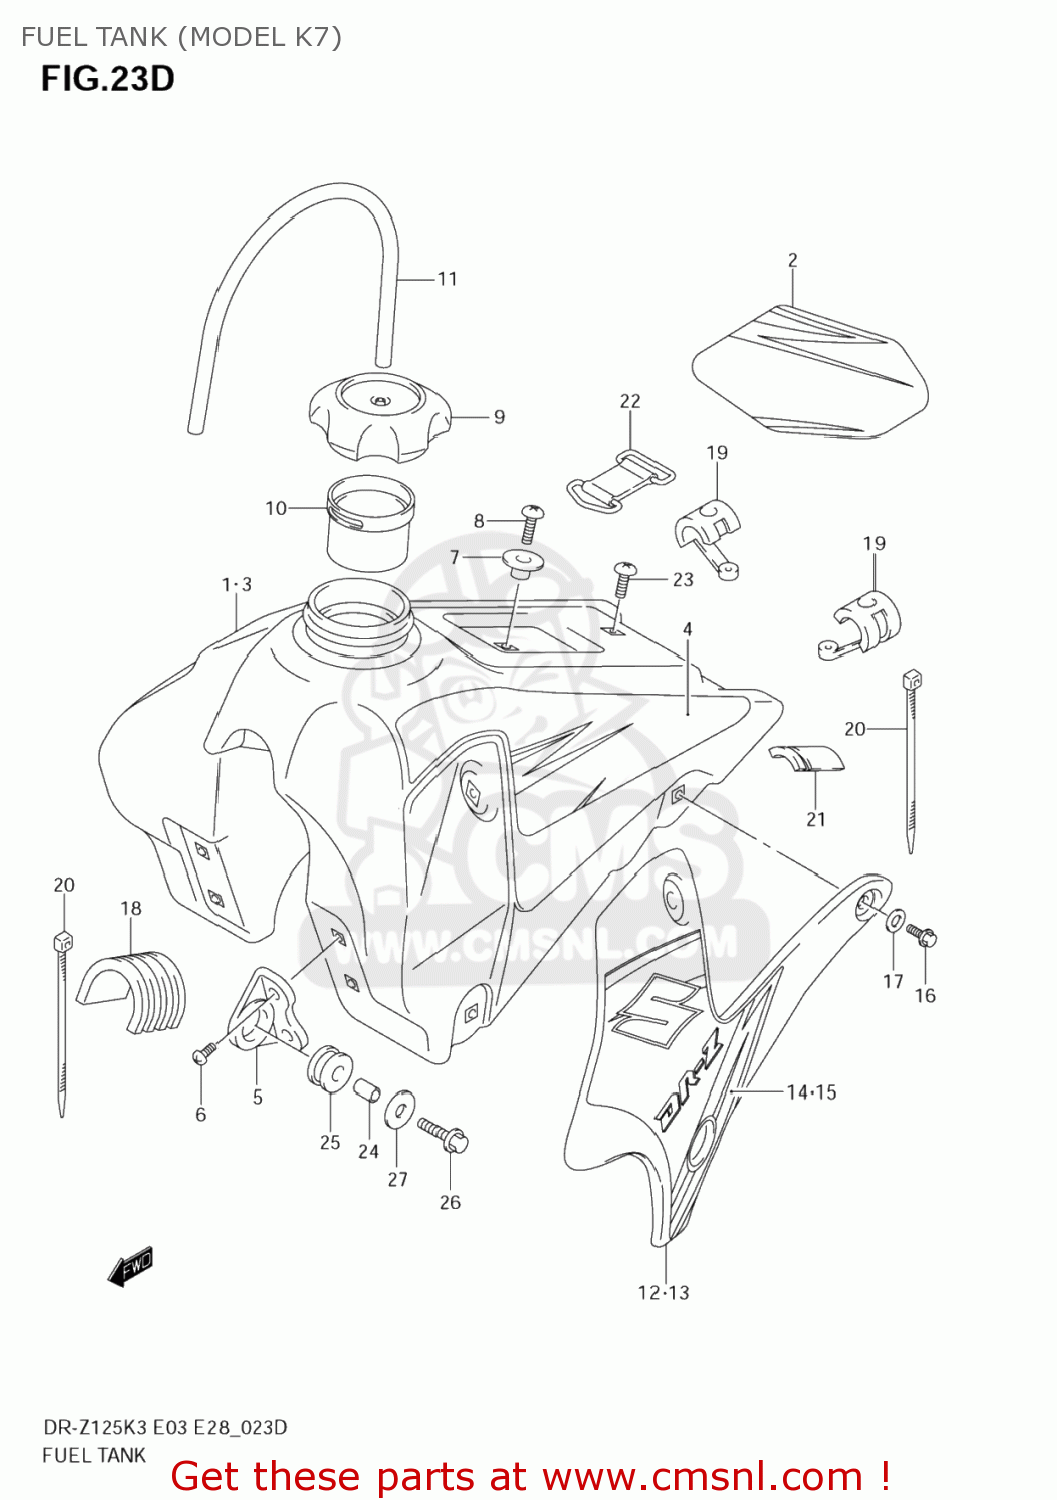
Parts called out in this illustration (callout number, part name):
1	TANK ASSY,FUEL(YELLOW)
2	TAPE SET,FUEL TANK
3	TANK ASSY,FUEL(BLACK)
4	TAPE SET,FUEL TANK
5	BRACKET,FUEL TANK FR
6	BOLT
7	HOOK,SEAT FR
8	SCREW
9	CAP ASSY,FUEL TANK FILLER
10	TUBE,FILLER INLET
11	HOSE(5X8.2X600)
12	COVER,FUEL TANK,R(BLACK)
13	COVER,FUEL TANK,L(BLACK)
14	TAPE,FUEL TANK COVER,R
15	TAPE,FUEL TANK COVER,L
16	BOLT
17	WASHER
18	CUSHION,FUEL TANK
19	CUSHION,FUEL TANK SIDE
20	CLAMP(L:300)
21	CUSHION,FUEL TANK RR
22	BAND,FUEL TANK RR
23	SCREW
24	SPACER(6.5X9X13.5)
25	CUSHION,FUEL TANK FR
26	SCREW
27	WASHER(6.5X24X1.2)
